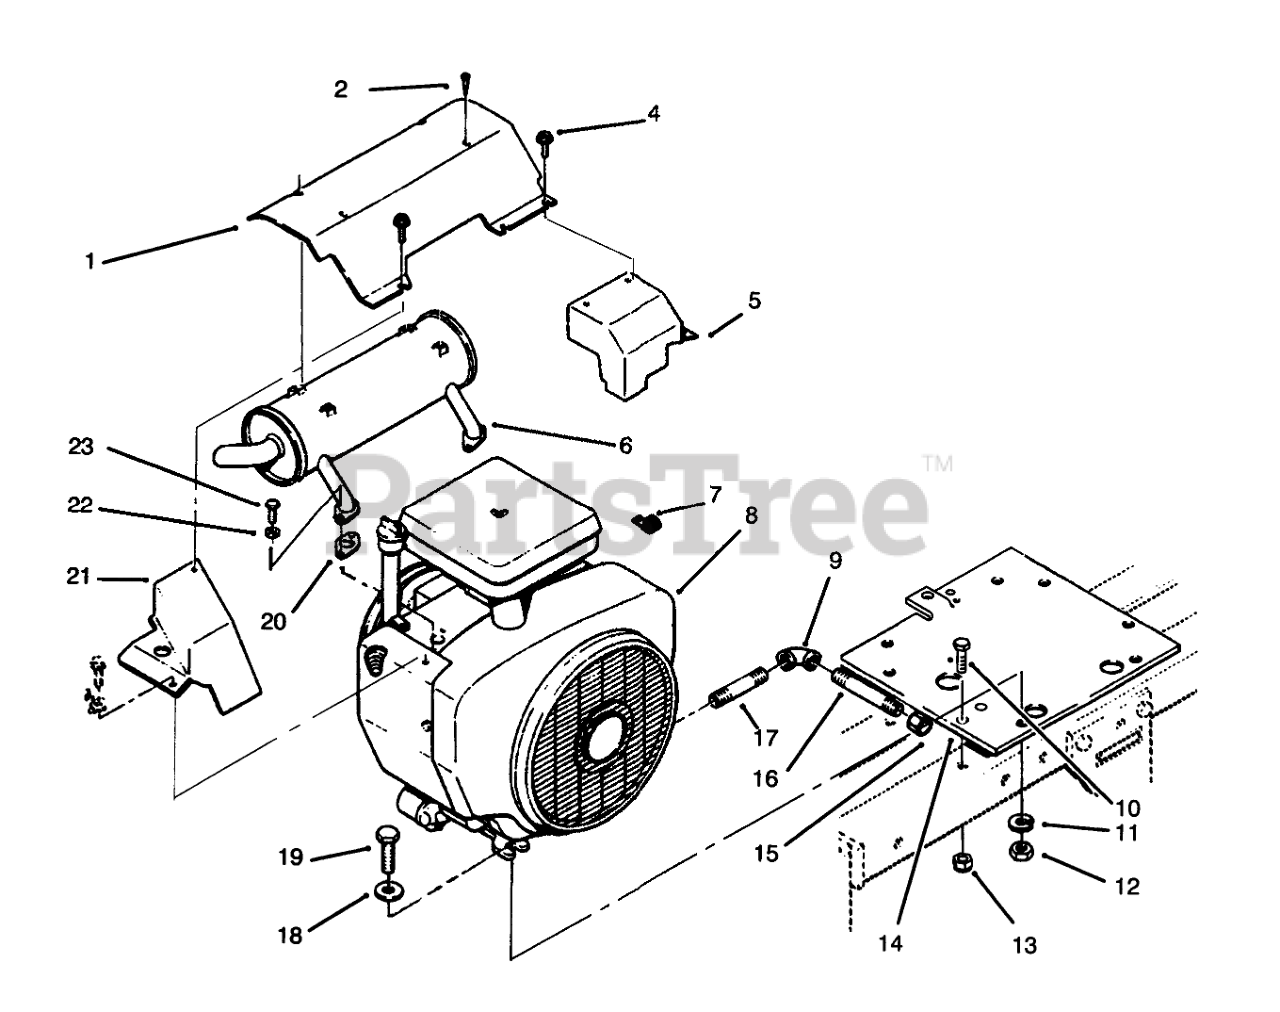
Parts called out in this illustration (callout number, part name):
1	BAFL DEFLCTORB
2	SCW 10-24 STAINLESS
4	SCREW
5	RH Exhaust Cover
6	MUFFLER-EXHAUST
7	CLIP
8	Engine-20HP
9	ELBOW 3/8 90 DEG
10	SCREW-HH
11	WASHER-LOCK
12	NUT-HEX
13	NUT-LOCK, NI
14	PLATE-ENGINE B
15	CAP-PIPE
16	PIPE-NIPPLE 3/8 X 4"
17	Pipe
18	WASHER-FLAT
19	SCREW-HH
20	GASKET
21	LH Exhaust Cover
22	WASHER-LOCK
23	SCREW-HH
